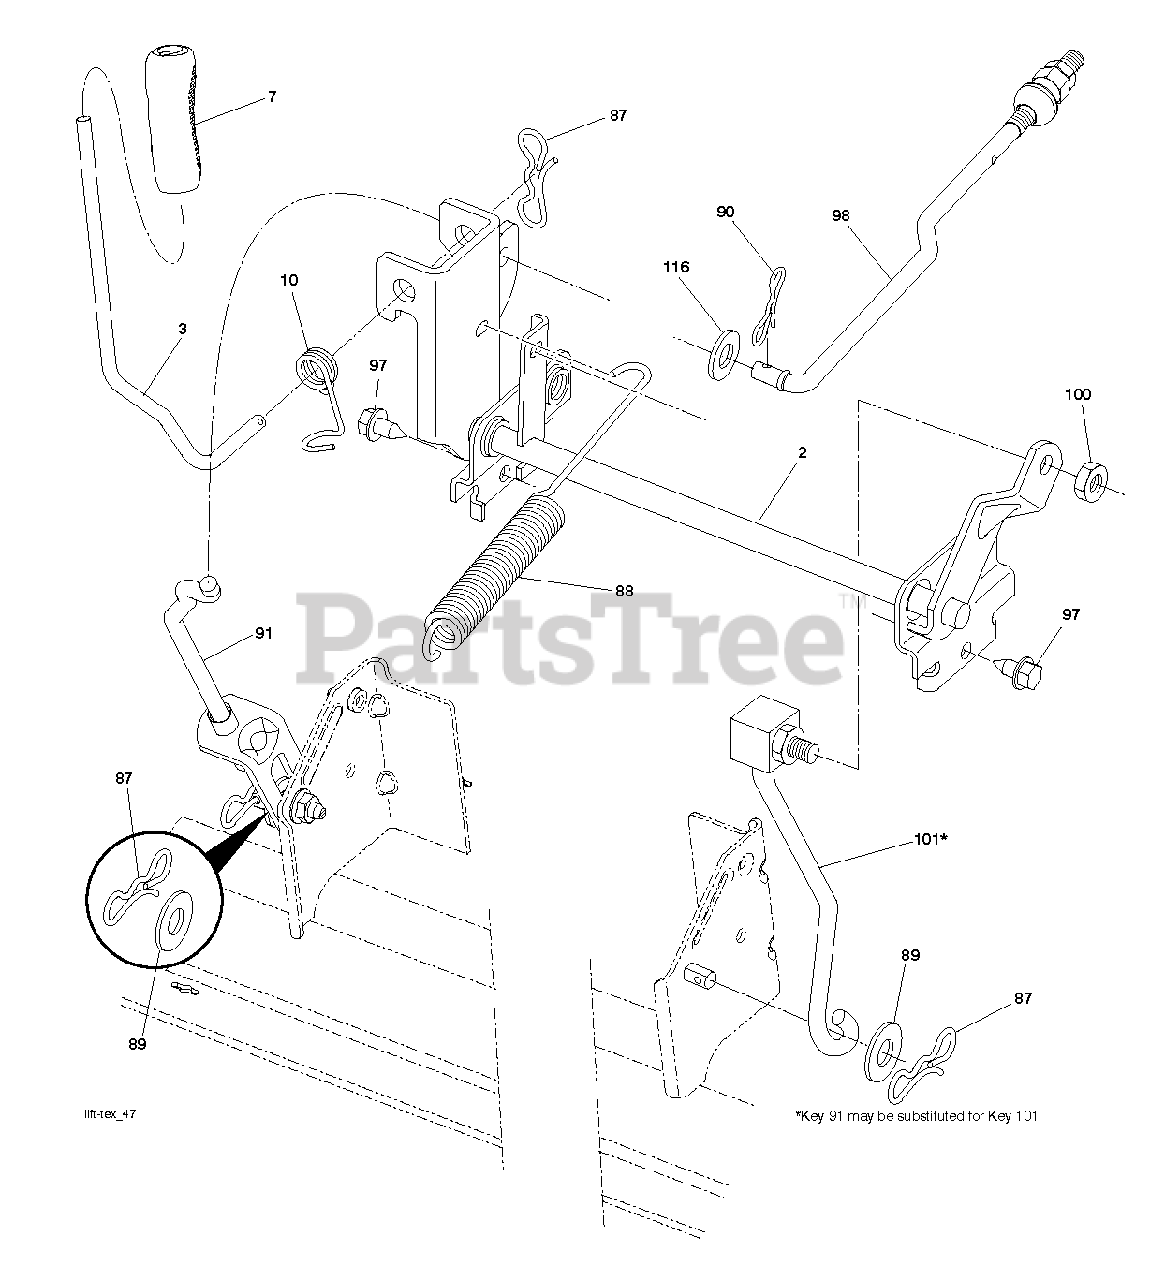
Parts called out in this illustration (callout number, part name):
2	SHAFT.ASM.CROSS.LIFT
3	LEVER.LIFT.HANDLE.LT
7	GRIP.HANDLE.LIFT.PVC.BLACK
10	SPRING.TORSION.LIFT.HANDLE
87	PIN.COTTER.7/16.BOW TI.
88	SPRING.LIFT.ASSIST
89	WASHER.CLEAR.ZINC
90	PIN.COTTER.5/16.BOW TI
91	LINK.ASM.LIFT.REAR
97	SCREW, 3/8-16X3/4
98	LINK.ASM.SUSP.FRONT.MW
100	LOCKNUT
101	LINK.ASM.LIFT.FIXE.38/42/46"
